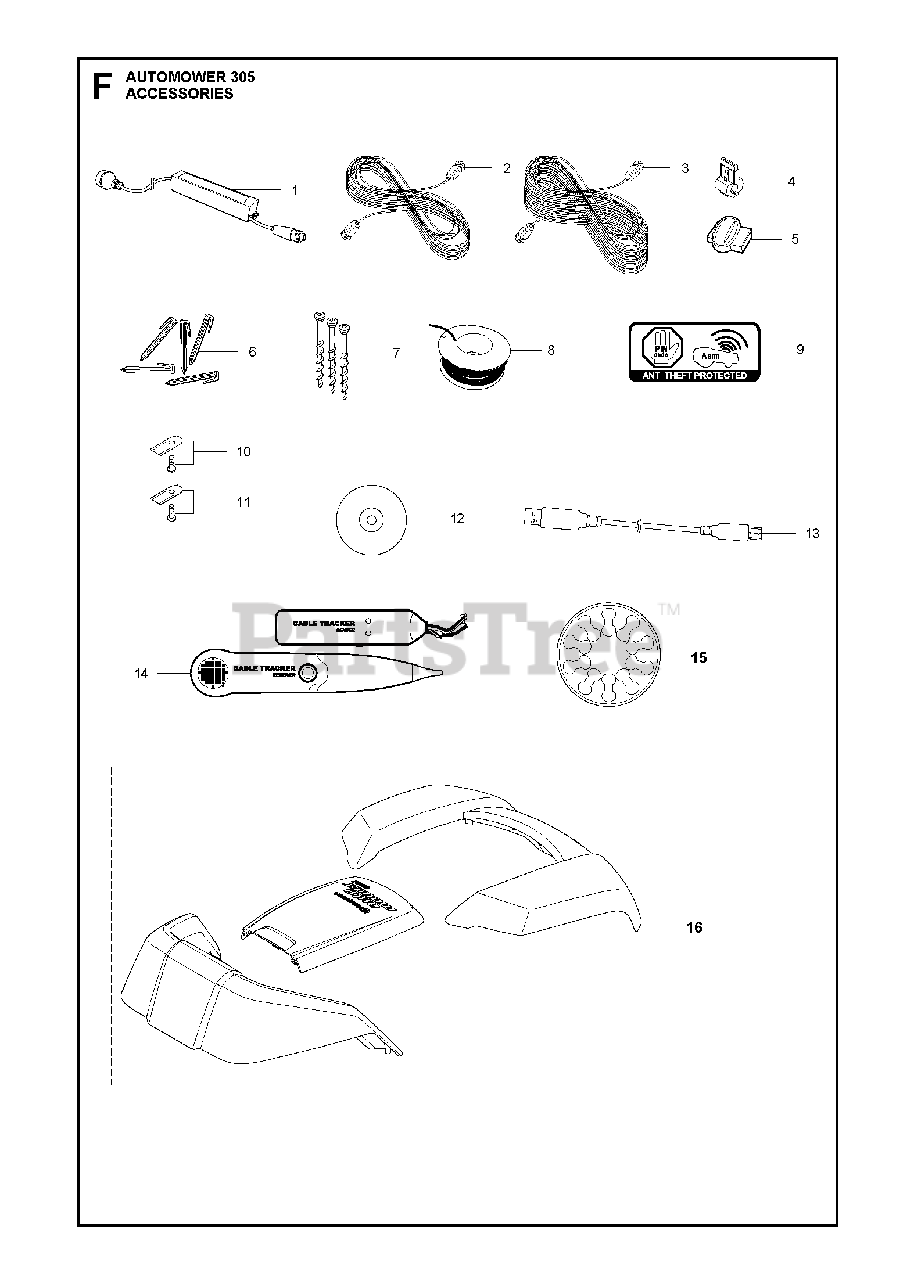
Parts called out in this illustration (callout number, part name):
4	BRAKER
4	Connector, 5 Pcs Blist
5	SPLICE KIT
5	Splicer Coupler, 5 Pcs
5	SPLICE CONNECTOR 50 PCS/PK
6	STAPLES (100 CT BAG)
6	STAPLE 100 PCS BLISTE
7	Screw Kit
7	SCREW 3 PCS, BLISTER PACK
8	LOOP WIRE 150M
8	WIRE 150M BLISTER
8	LOOP WIRE 250M
10	BLADE
10	BLADE KIT
10	BLADE - 30 PCS
10	BLADE - BULK PACK 500 PCS
11	BLADE 9PCS EXTRA THICK
11	Blade Set, 9 Piece Extra Thick
11	BLADE CARBON STEEL, THICK BLAD
11	BLADE 300PCS -SINGLE HOLE THIC
14	TEST EQUIPMENT
